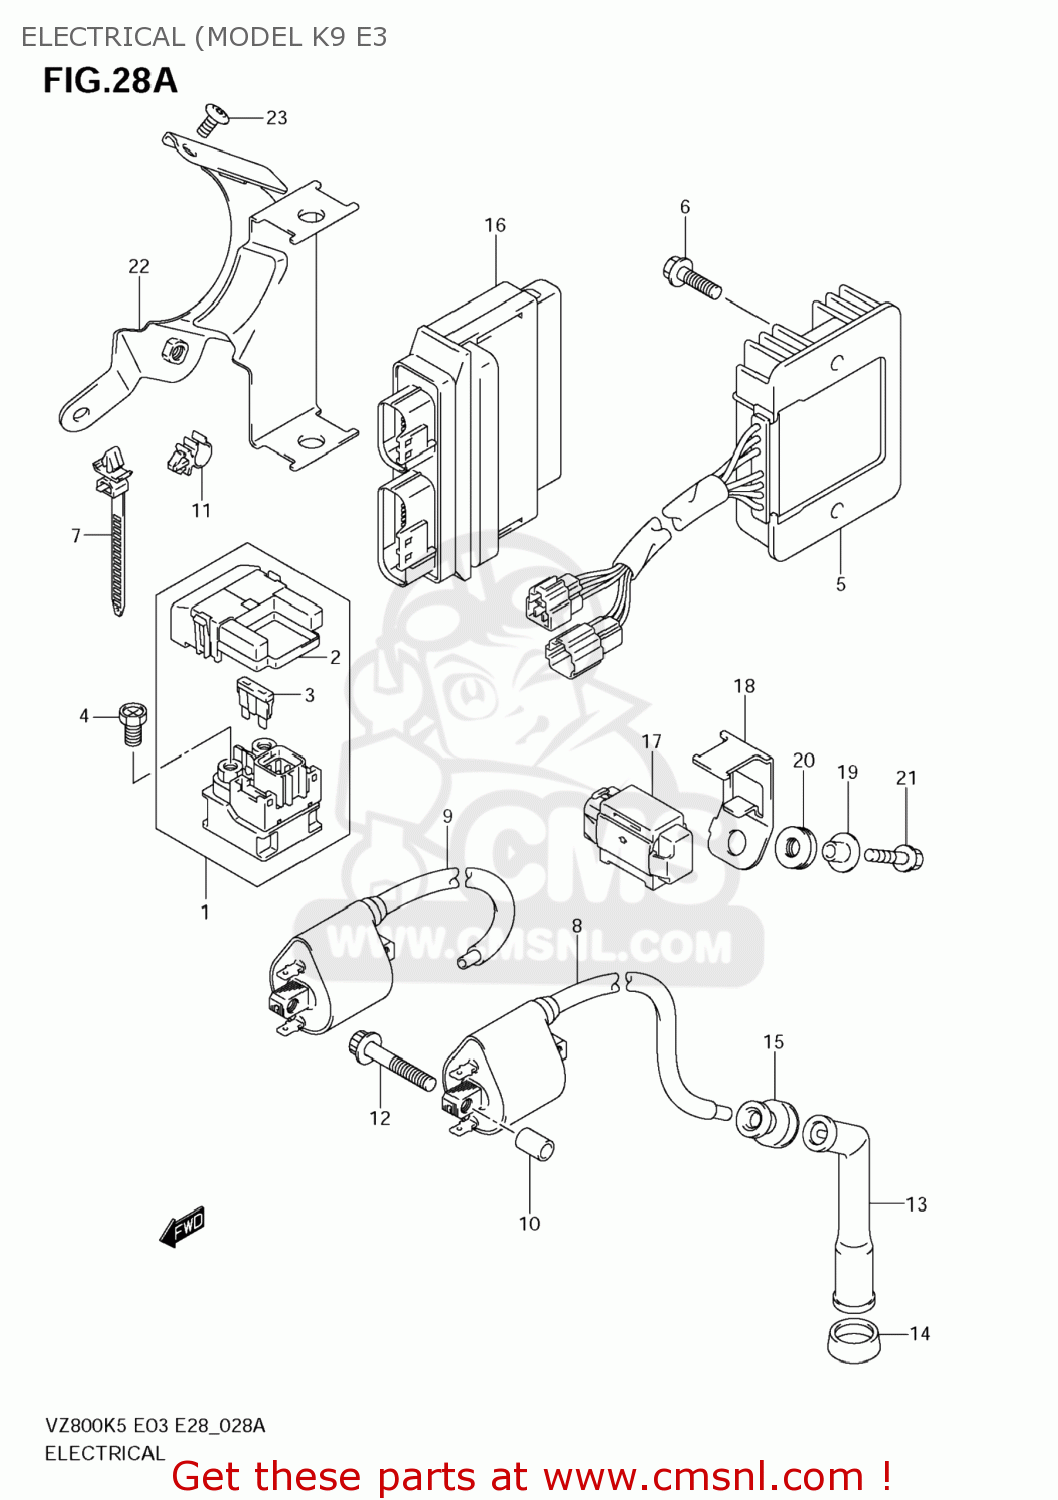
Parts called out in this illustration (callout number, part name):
1	RELAY ASSY,STARTING MOTOR
2	COVER
3	FUSE(30A)
4	SCREW(6X8)
5	RECTIFIER ASSY
6	SCREW
7	CLAMP(L:90)
8	COIL ASSY,IGNITION
9	COIL ASSY,IGNITION
10	SPACER(6.4X10X18)
11	CLAMP
12	BOLT(5X35)
13	CAP,SPARK PLUG
14	SEAL,SPARK PLUG
15	SEAL,HIGH TENSION CORD
16	CONTROL UNIT,FI
17	SENSOR ASSY,FUEL CUT
18	BRACKET,FUEL CUT SENSOR
19	SPACER(6.2X8.4X6.9)
20	CUSHION
21	BOLT
22	BRACKET,FI CONTROL UNIT
23	SCREW(6X12)
